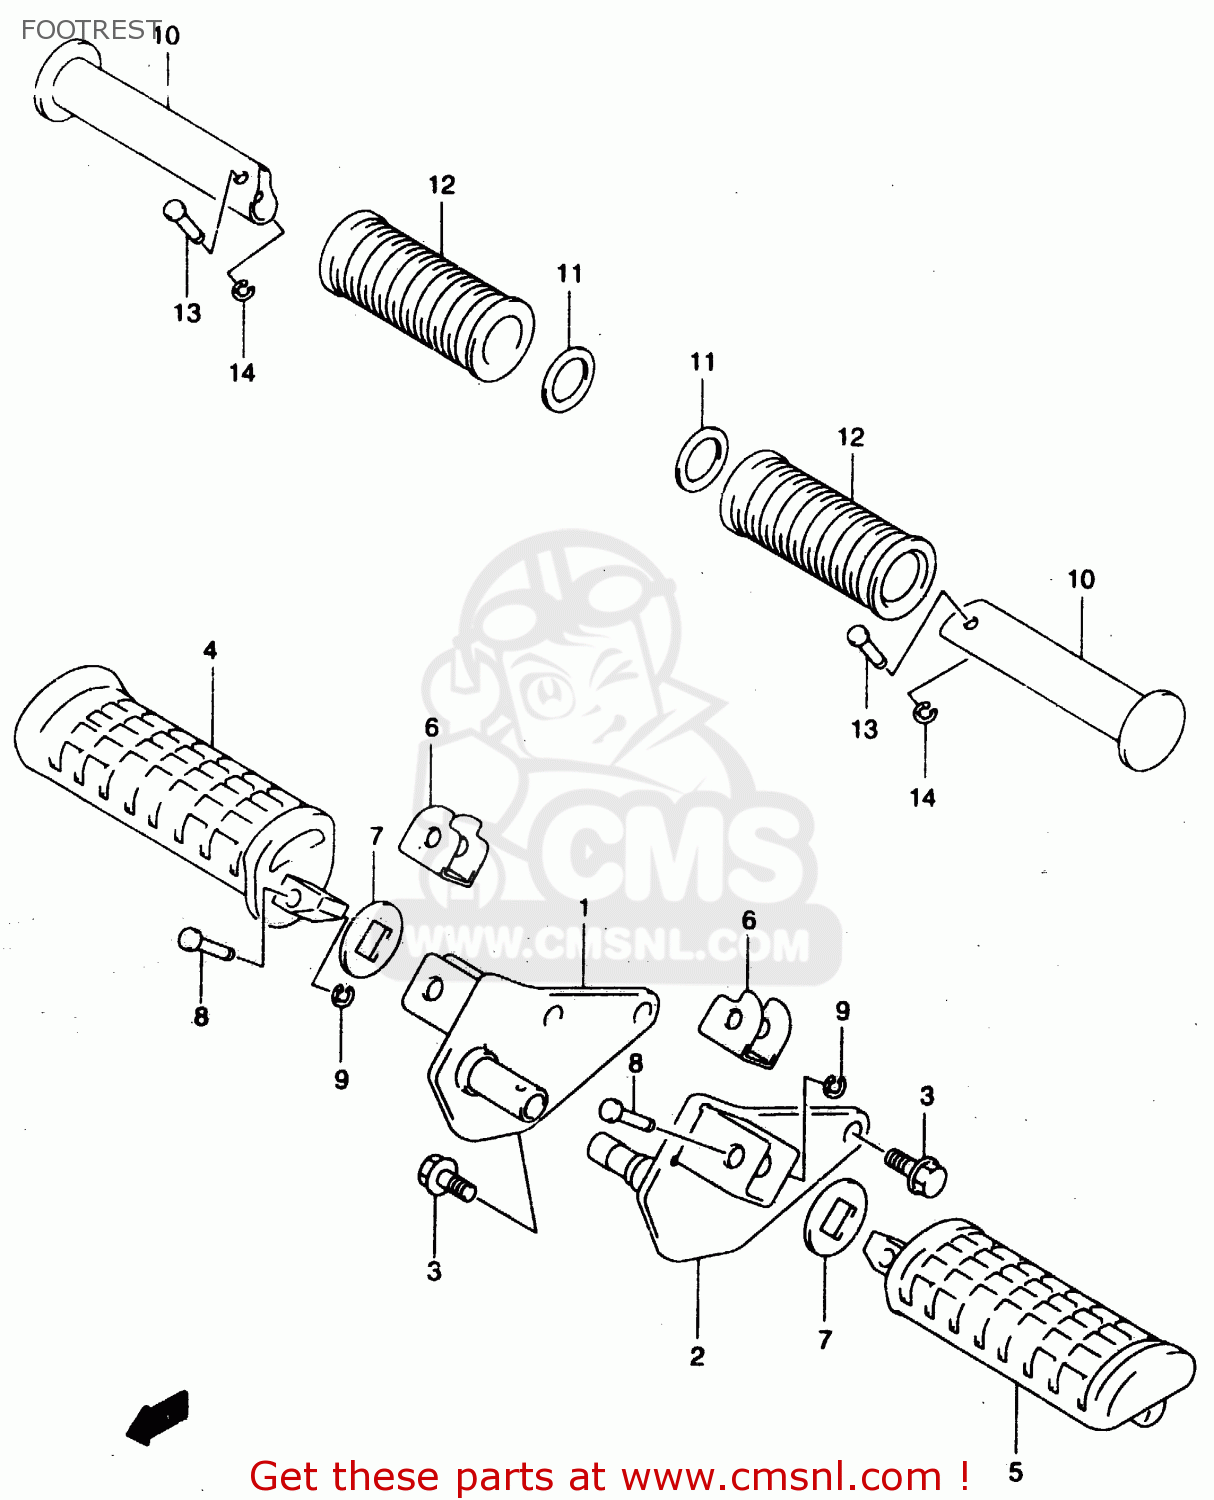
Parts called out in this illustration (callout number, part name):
1	BRACKET,FR FOOTREST,R
2	BRACKET,FR FOOTREST,L
3	BOLT
4	RUBBER,FRONT FOOTREST,RIGHT
5	RUBBER,FRONT FOOTREST,LEFT
6	CUSHION,FR FOOTREST
7	WASHER,FOOTREST RUBBER
8	PIN
9	E-RING
10	BAR,PILLION FOOTREST
11	WASHER(19.5X32X2)
12	RUBBER,PILLION FOOTREST
13	PIN,PILLION FOOTREST
14	E-RING
